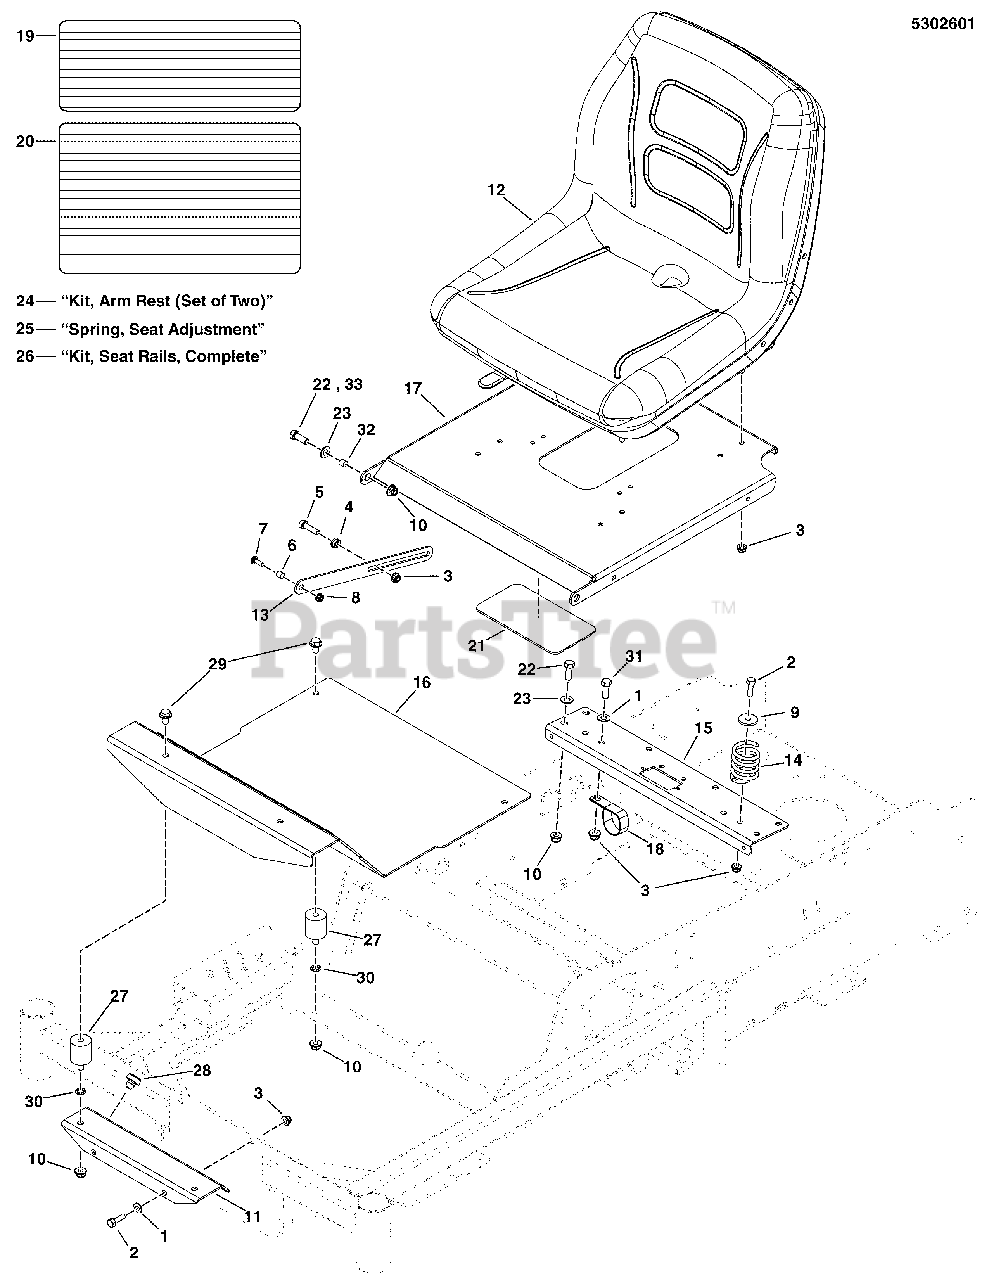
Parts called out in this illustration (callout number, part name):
1	WASHER, 5/16 SAE
2	BOLT, 5/16-18 X 1 GD5 YZ
3	NUT, 5/16-18 HEX NYLOCK FLANGE
4	NUT, 5/16-18 HEX SERRATED FLANGE (SMALL)
5	BOLT, 5/16-18 X 1-1/4, CARRIAGE YZ
6	SPACER, .25 X .37 X .25
7	BOLT, 1/4-20X.750, SQ
8	NUT, 1/4-20 HEX NYLOCK FLANGE (5025391)
9	WASHER, .34 X 1.25 X 10 GA
10	NUT, 3/8-16 HEX NYLOCK FLANGE
11	PLATE, SIO FLOOR MOUNT - RED
12	SEAT, NO ARM REST
13	SEAT PLATE, STOP - BLK
14	SPRING, SEAT SUPPORT
15	MOUNT, SEAT STOP - RED
16	PLATE, FOOT REST - RED
17	WELD, PLATE, SEAT MOUNT - RED
18	VINYL CLAMP
19	SAFETY WALK, FLOOR REST, 16.00 X 6.00
20	SAFETY WALK, FLOOR PLATE, S50X, 10X17.13
21	SAFETY WALK, 4.00 X 7.50
22	BOLT, 3/8-16 X 1 GD5 YZ
23	WASHER, 3/8 SAE
24	ARM REST (SET OF TWO) (SV)
25	SPRING, EXTENSION, SEAT ADJUSTMENT (BLK OR SLVR)
26	KIT, SEAT RAILS (COMPLETE)(SV)
27	MNT, VBRTN, 30 DURO
28	MNT, VBRTN, RBBR
29	BOLT, 3/8-16 X 5/8, SERRATED UNDER HEAD
30	WASHER, 3/8" ID, INTERNAL TOOTH
31	BOLT, 5/16-18 X 3/4 GD5
32	FLANGED BUSHING, 3/8 ID X .63 OD X .55 LG
33	BOLT, 3/8-16 X 1-1/2 GD5 YZ
